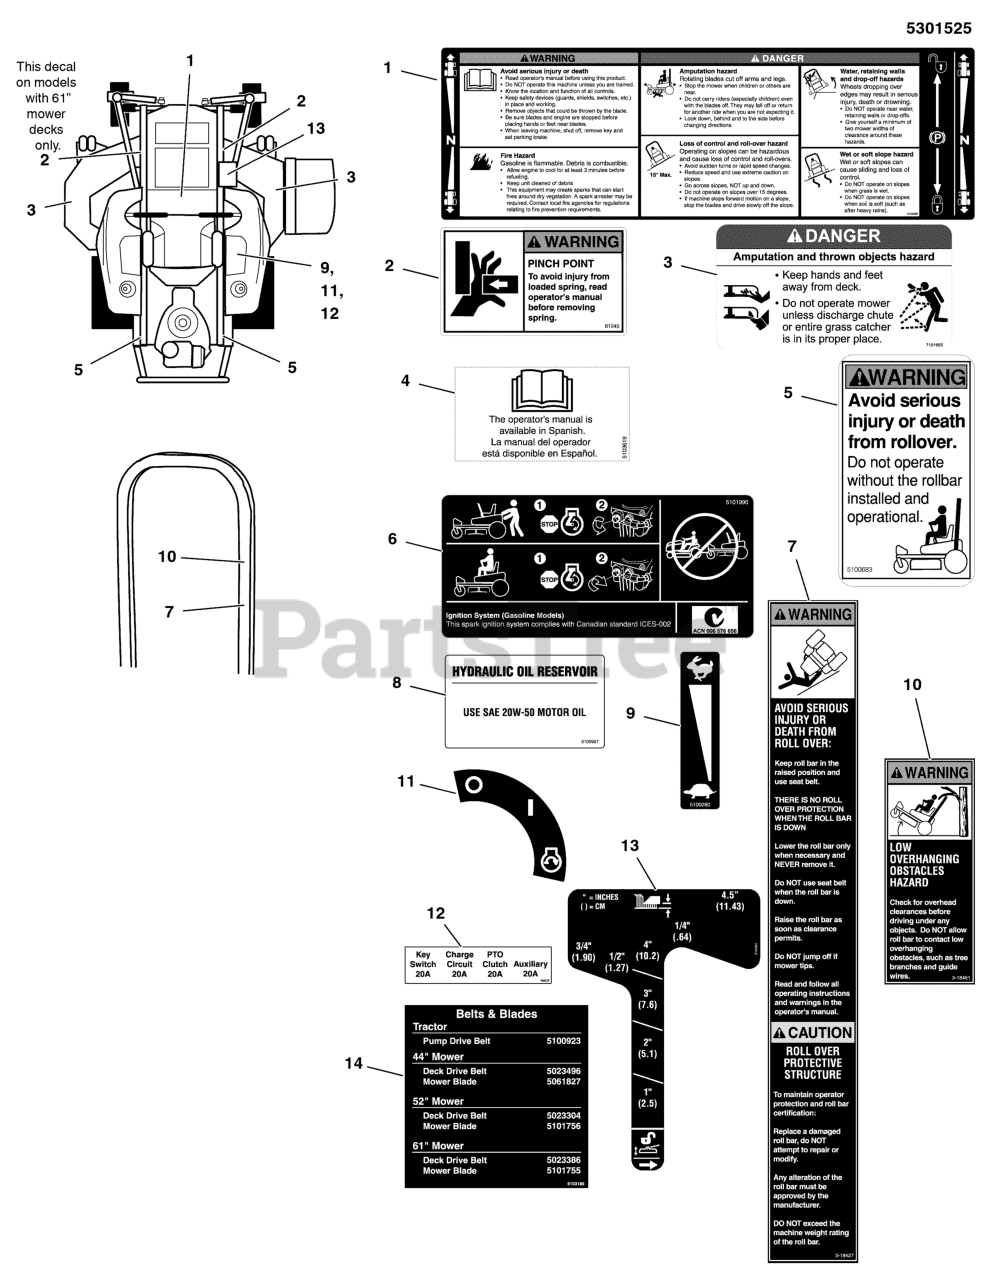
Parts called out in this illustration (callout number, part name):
1	DECAL, MAIN SAFETY
2	DECAL, PINCH POINT
3	DECAL, DANGER DO NOT OPERATE W/O DEFLECT
4	DECAL, MANUAL AVAIL IN SPANISH
5	DECAL, WARNING, ROLL BAR
6	DECAL, CZT HYRDO RELEASE
8	DECAL, HYDRAULIC OIL, SAE 20W50
9	DECAL, THROTTLE CONTROL
10	DECAL, WARNING OVERHANG, ROPS
11	DECAL, IGNITION SWITCH
12	DECAL, FUSE LOCATION
13	DECAL, DECK HEIGHT, IS500Z
14	DECAL, BELT & BLADE, IS500Z
